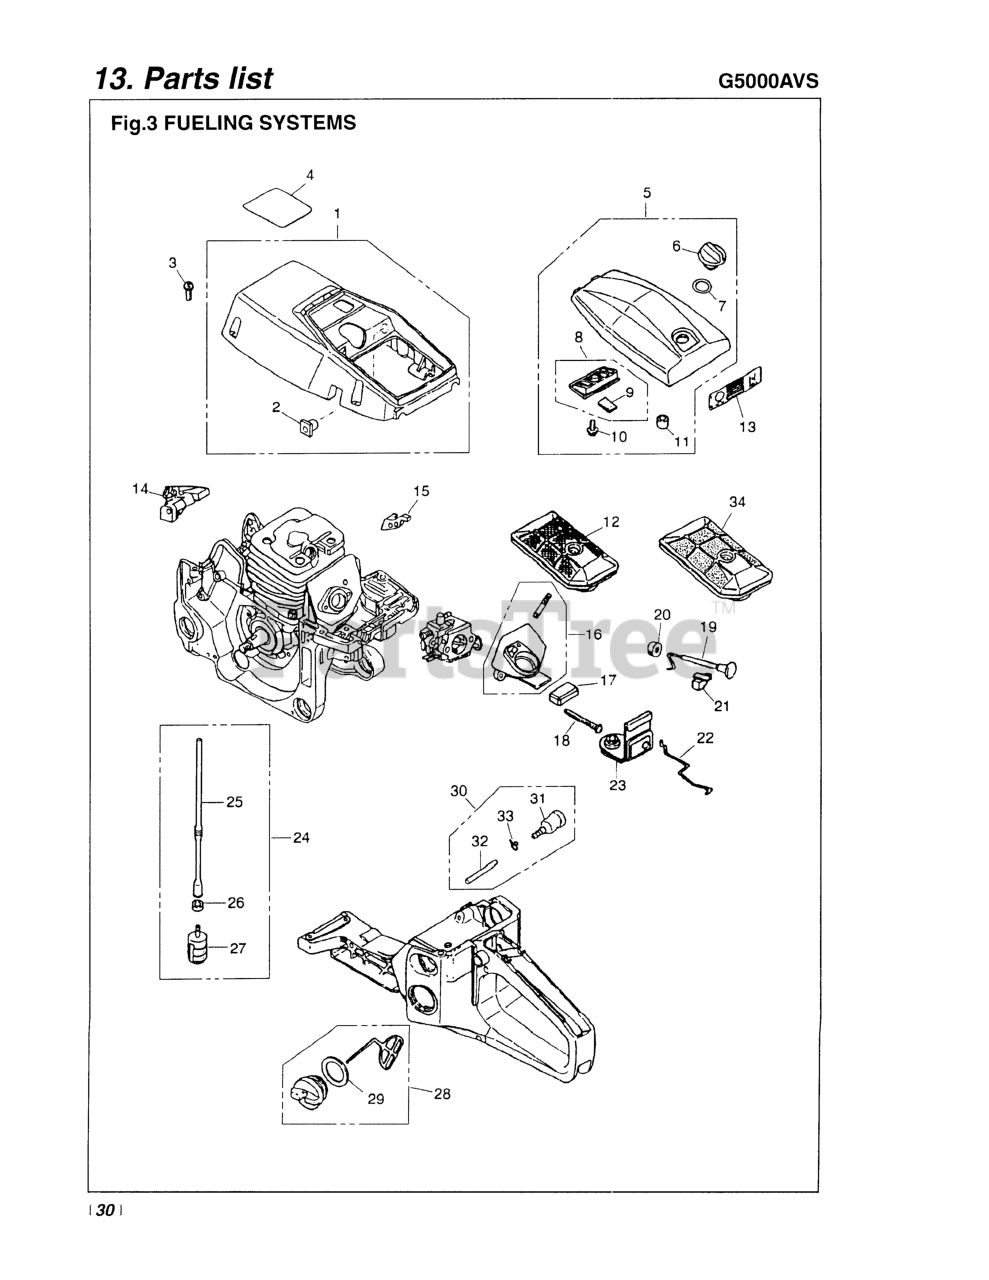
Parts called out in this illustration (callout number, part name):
1	CYLINDER COVER
3	SCREW (REPLACES 2616-24320)
5	COVER COMP (RPLS -83304)
7	GASKET, KNOB
8	CLEANER COMP
10	SCREW
12	CLEANER, AIR
16	MANIFOLD COMPLETE
17	SUPPORTER
19	ROD, CHOKE
21	GUIDE
22	ROD, THROTTLE
27	FILTER ASSY
28	CAP ASSEMBLY
29	GASKET
30	BREATHER ASSEMBLY
31	BREATHER (USE 2670-34500)
33	CLIP (REPLACES 2841-31280)
34	CLEANER, AIR (FLOCKED)
